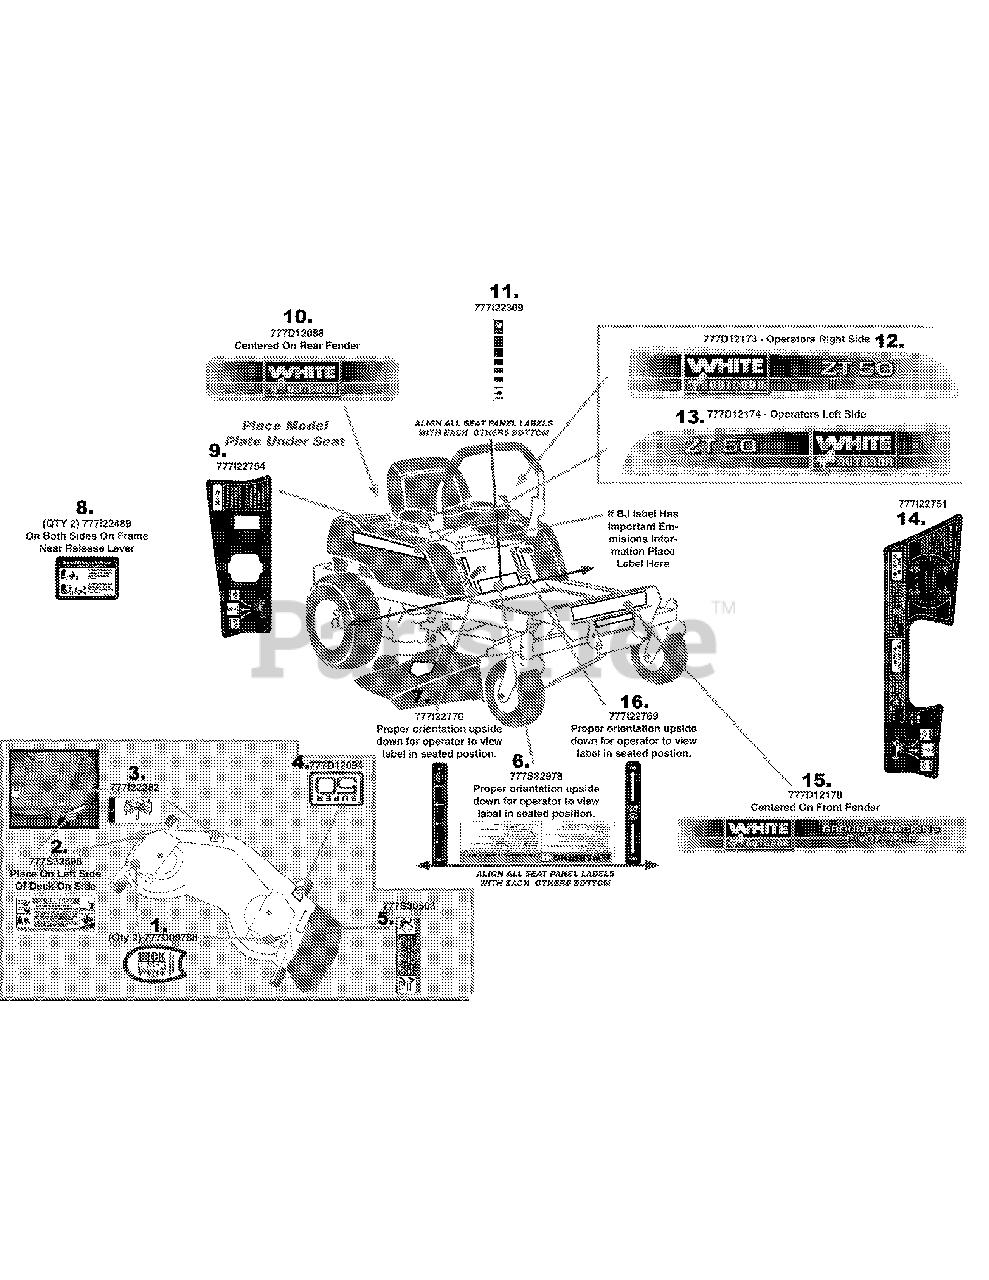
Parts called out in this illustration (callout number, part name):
1	LABEL:RIDER:WHITE
2	LABEL-RZT DECK WARNG STRAIGHT
3	LABEL-BELT ROUTE
4	LABEL-RIDER TOP DECK 50" CUT
5	LABEL-DANGER CHUTE
6	LABEL-COMMON WARNING
7	LABEL-HANDLE HEIGHT
8	LABEL-TRNMSN RELEASE
9	LABEL-RH CONTROL
10	LABEL-RIDER REAR FENDER WHITE
11	LABEL-THROTTLE
12	LABEL-RZT SD POD WHITE 50" RH
13	LABEL-RZT SD POD WHITE 50" LH
14	LABEL-LH CONTROL
15	LABEL-RZT FRONT WHITE LOGO
16	LABEL-PARK BRAKE
